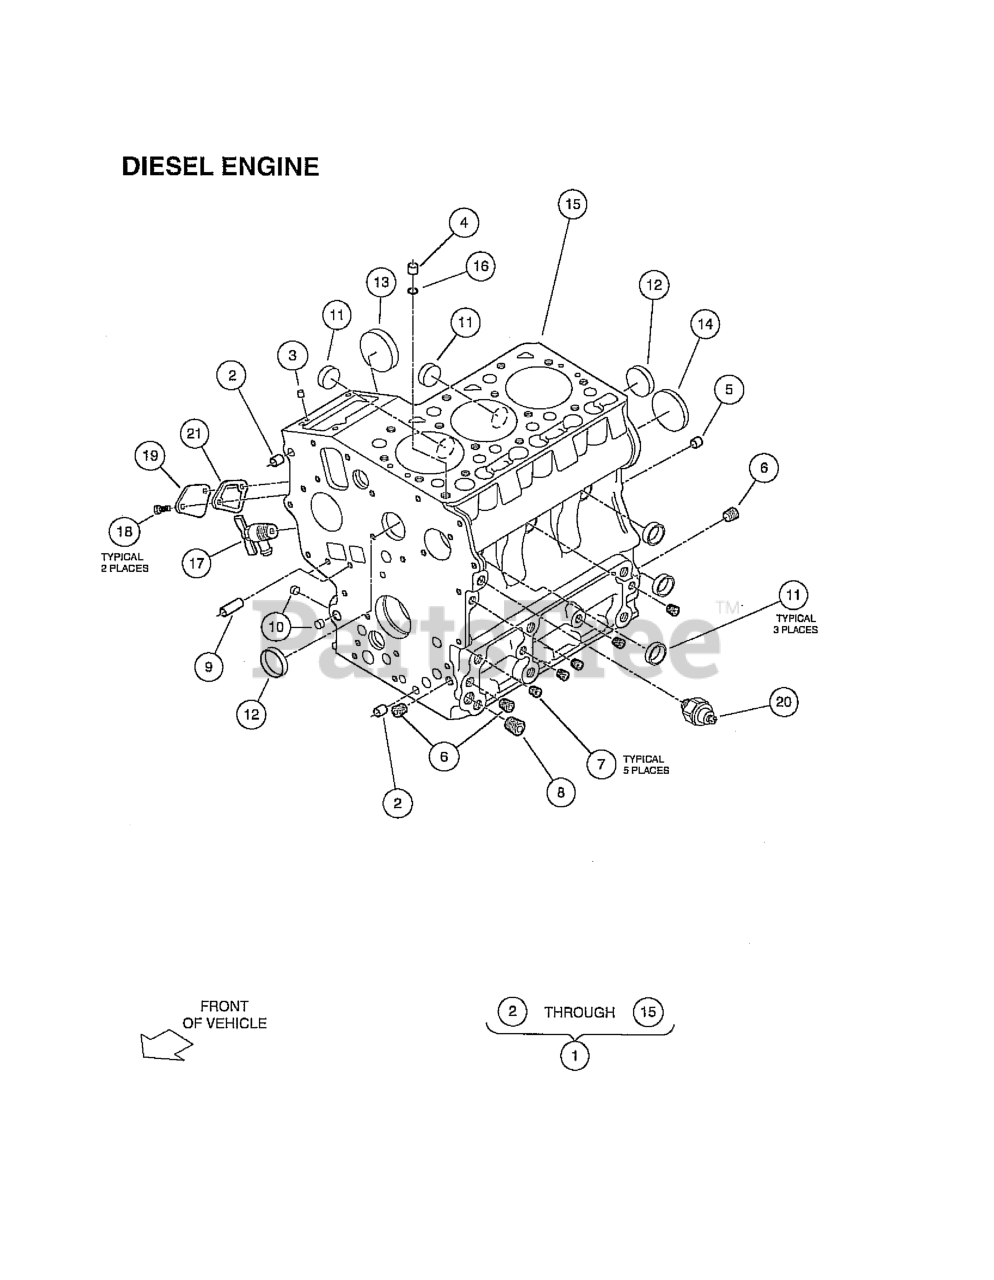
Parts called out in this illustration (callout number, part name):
1	ENGINE BLOCK
2	PIN, PIP, DIA 8 X 14
3	PIN, STRAIGHT, DIA 5 X 10
4	PIN, PIPE, DIA 7 X 14
5	PIN, STRAIGHT, DIA 8 X 16
6	PLUG, 1/8" NPT
7	PLUG, 3/32" NPT
8	PLUG, 1/4" NPT
9	PIN, PIPE, DIA 8 X 11
10	CAP, SEALING, SMALL
11	CAP, SEALING, MED
12	CAP, SEALING, LARGE
13	COVER, FUEL CAMSHAFT
14	PLUG, EXPANSION
16	O-RING, 8 X 7
17	ASSY COCK, DRAIN
18	BOLT, M6X1X20
19	PLATE, ENGINE BLOCK
20	SWITCH, OIL PRESSURE
21	GASKET, FUEL PUMP, D722
